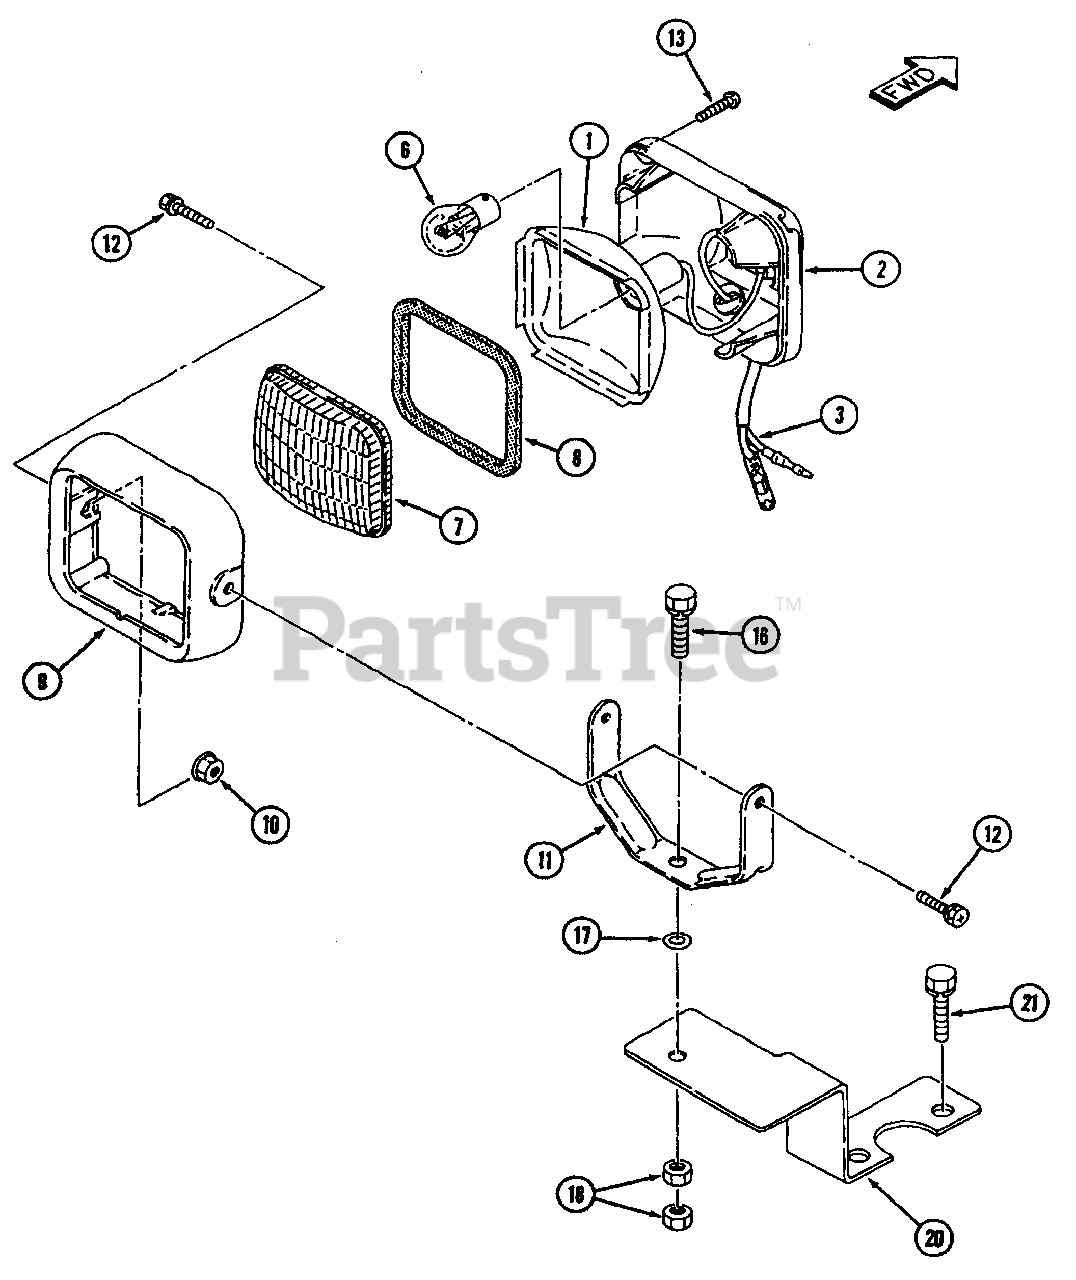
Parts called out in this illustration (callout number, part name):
1	Reflector, Component
2	Housing, Component
3	Lead, Component
9	Rim
13	Screw, Tapping
